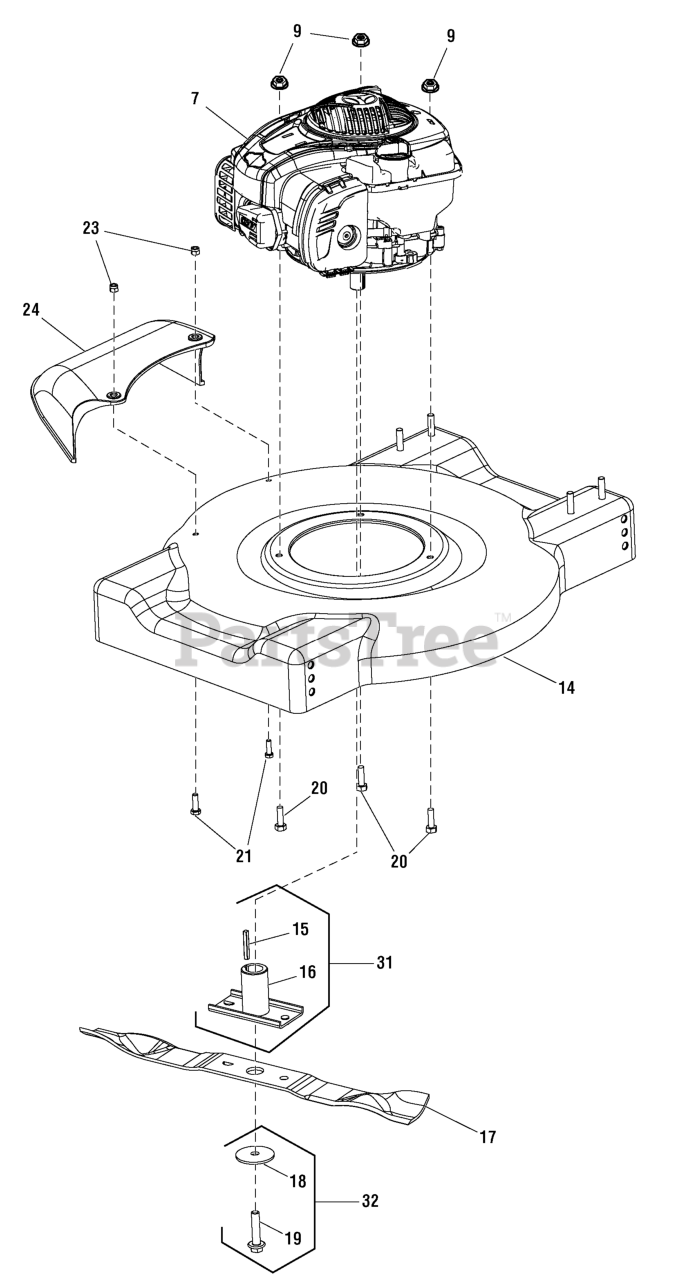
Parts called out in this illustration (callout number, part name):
7	* ENGINE, Briggs & Stratton 450E Series
9	NUT, M8
16	ADAPTER, Blade
18	WASHER, Flat
19	BOLT, Blade, 3/8-24
20	BOLT, Flange, M8 x 35
21	BOLT, M6 x 20
23	NUT, M6
24	CHUTE, Side Discharge
31	KIT, Blade Adapter
32	KIT, Hardware, Blade Bolt
